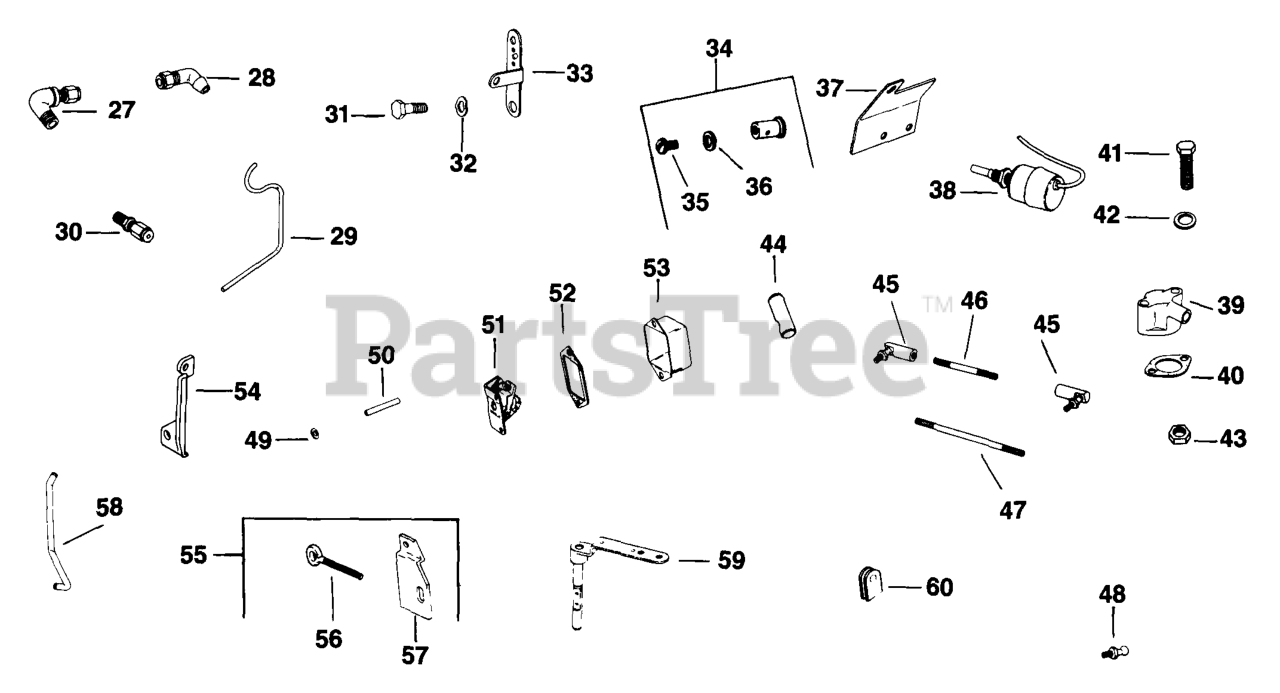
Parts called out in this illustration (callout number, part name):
29	LINE - DISCONTINUED
39	BREATHER - DISCONTINUED
44	BODY - DISCONTINUED
46	STUD,#10-32X2-1/8"
48	JOINT-USE 237130-S
49	DIAPHRAGM-DISCONTINUED
51	BREAKER - DISCONTINUED
52	GASKET, POINT COVER
55	KIT - DISCONTINUED
56	SCREW - DISCONTINUED
57	BRACKET - DISCONTINUED
